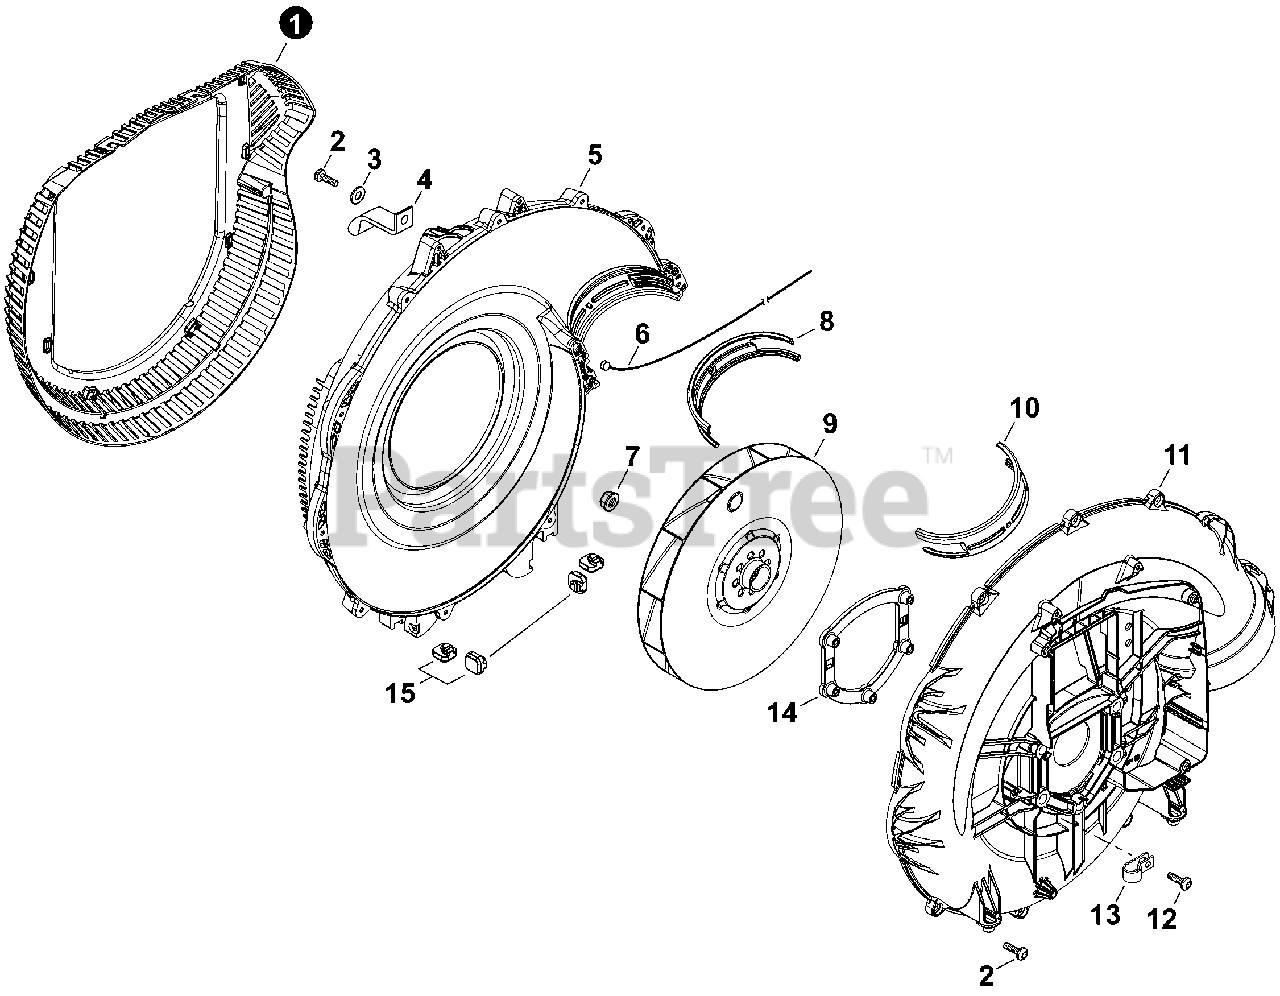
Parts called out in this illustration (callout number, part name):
1	GUARD, DEBRIS
2	BOLT, TORX 5x20
3	WASHER 5.5x16x0.8
4	STRAP, SAFETY
5	COVER, FAN
6	WIRE, ANTI-STATIC
7	NUT, FLANGE 10x1.25
9	FAN, BLOWER
11	CASE, FAN
12	BOLT, TORX 5x16
13	CLIP
14	PLATE, ENGINE
15	CUSHION
